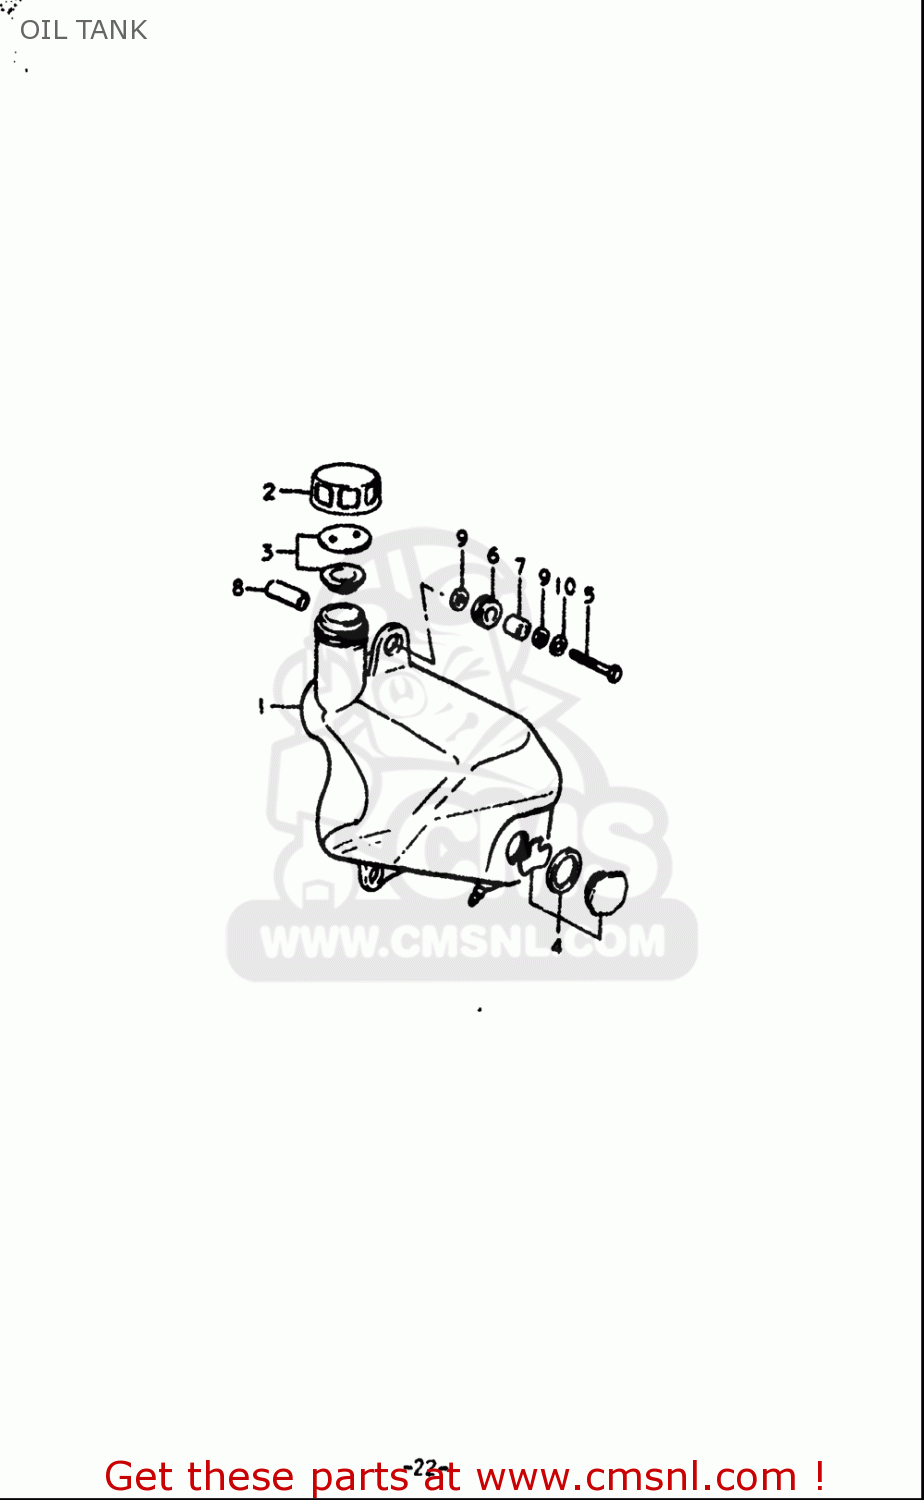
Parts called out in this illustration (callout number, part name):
2	CAP,OIL TANK
3	GASKET SET (NAS)
4	LENS SET,OIL LEVEL
5	BOLT
6	CUSHION
7	SPACER(6.5X10X27.5)
8	SPACER(6.5X10X10)
9	WASHER(6.5X18X1.6)
10	WASHER,LOCK
